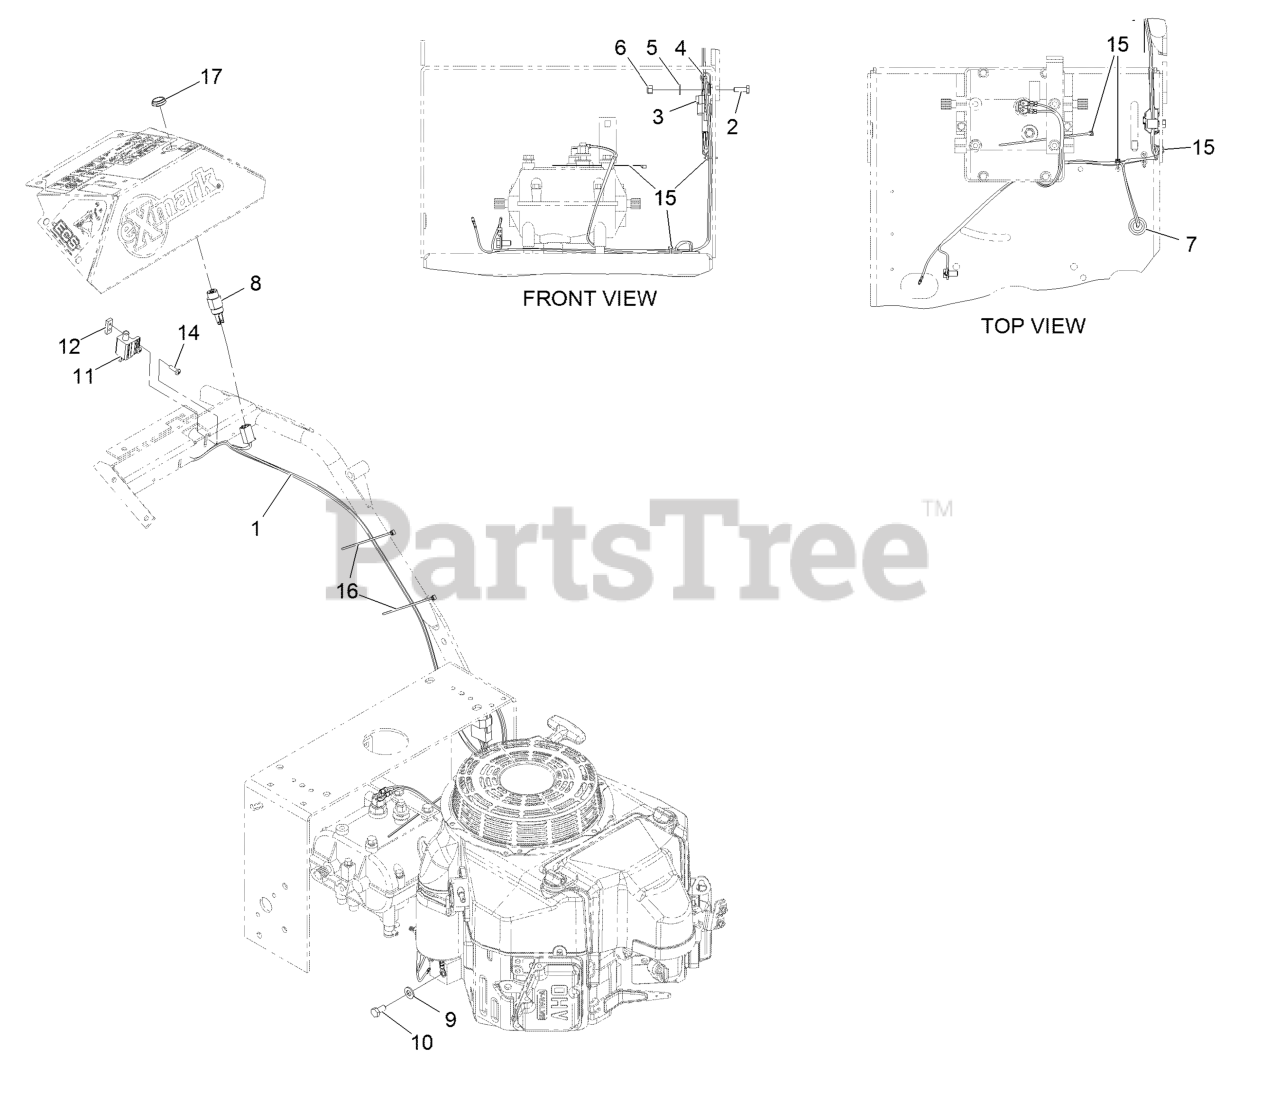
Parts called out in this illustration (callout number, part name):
1	Harness-Wire
2	Screw-HH 1/4-20 X 3/4
3	Module-Interlock
4	Clip-Loom 1/2
5	Washer-1/4 SAE
6	Nut-Nyloc 1/4-20
7	Grommet
8	Switch & Key (Includes Nut & Washer)
10	Screw-HH M8-1.25 X 16Mm
11	Switch-N.O.
12	Plate-Tapped
14	Screw-PPH #10-24 X 5/8
15	Tie-Cable 5 1/2 (Small)
16	Tie-Cable 5 1/2 (Small)
17	Nut-Ignition
